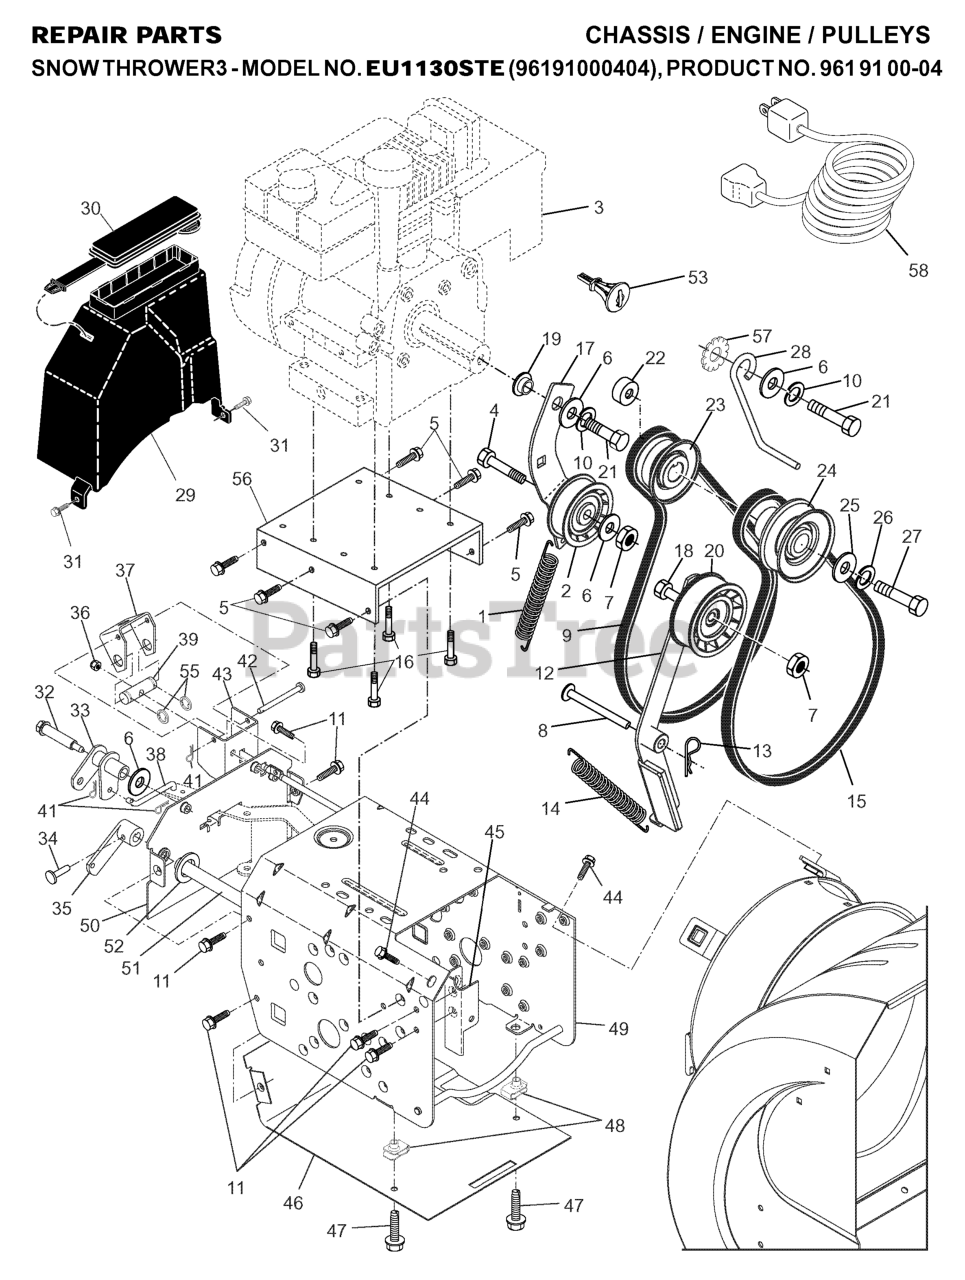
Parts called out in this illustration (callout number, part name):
1	RP SPRING, TRACTION IDLER
2	PULLEY.W/SPACER.2.25
4	BOLT.5/16-18X1-1/4 FULL.THREAD
5	SELF-TAPPING SCREW 5/16-18X3/4
6	STEEL WASHER
7	LOCKNUT 5/16-18
8	PIN, IDLER PIVOT
10	WASHER, LOCK 5/16
11	SCREW, HEX HEAD 5/16-18 X 1/2
12	ARM ASSEMBLY, IMPELLER IDLER
13	RETAINER CLIP PM
14	SPRING, BRAKE
15	V-BELT
16	BOLT 3/8-16X1-1/8
17	IDLER ARM
18	HEX BOLT
19	BUSHING, IDLER PIVOT
20	PULLEY.W/SPACER.2.75
22	SPACER, ENGINE PULLEY
23	PULLEY,ENGINE TRACTION DRIVE
24	PULLEY.ENG.IMPELLER.SNOW
25	WASHER, FLAT 3/8
26	LOCKWASHER
27	SCREW, HEX HD 3/8-24 X 1-3/8
28	BELT.GUIDE.RH
29	BELT COVER ASSEMBLY
30	COVER.STORAGE.SNOW
31	SCREW, HEX HEAD 1/4-20
32	BOLT, SHOULDER 5/16-18
33	BELLCRANK SHIFTER
34	CLEVIS PIN
35	ARM, AUGER CONTROL
36	NUT.LOCK.5/16-18
37	BRACKET, PIVOT
38	LINK, SPEED CONTROL
39	TRUNNION, TRACTION
41	RETAINER CLIP
42	PIN, PIVOT BRACKET
44	SCREW 3/8-16X1
45	BRACKET, IDLER PIVOT
46	PAN, FRAME BOTTOM
47	Screw, Hex Head 5/16-18 x 3/4
48	NUT.SPEED.5/16-18
49	SWITCH.PTO.T
50	PLATE, FRAME END
51	SHAFT, AUGER CONTROL
52	THRUST WASHER
53	KEY.PUSH/PULL.B&S.283707
55	RETAINING RING LT
56	PLATE, ENGINE MOUNTING
57	WASHER EXT TOOTH LOCK 5/16
58	CORD.ELECTRIC.10FT.120V.SNOW
